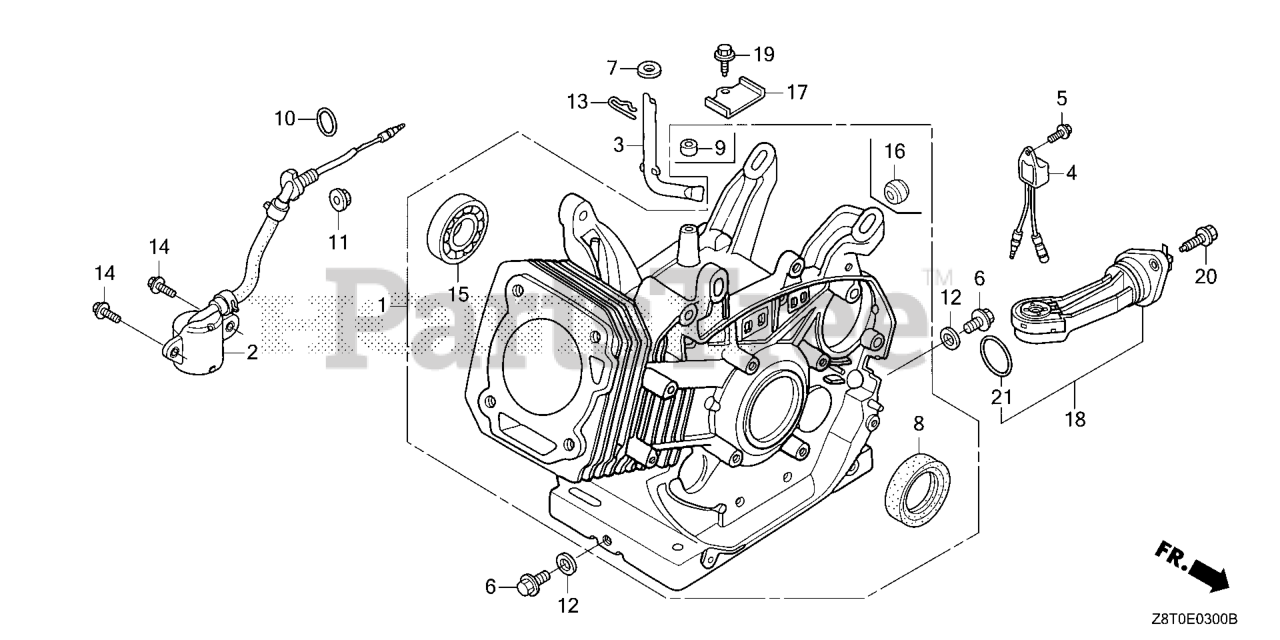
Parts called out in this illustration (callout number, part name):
1	CYLINDER ASSY. (ALERT)
2	SWITCH ASSY., OIL LEVEL
3	SHAFT, GOVERNOR ARM
6	BOLT, DRAIN PLUG
7	WASHER (8.2X17X0.8)
8	OIL SEAL (35X52X8) (NOK)
8	OIL SEAL (35X52X8)
9	OIL SEAL (8X14X5)
10	O-RING (14MM) (ARAI) Use up to Engine SN 2949254.
11	NUT, FLANGE (10MM)
12	WASHER, DRAIN PLUG (12MM)
13	PIN, LOCK (10MM)
14	BOLT, FLANGE (6X12) Use up to Engine SN 1543277.
15	BEARING, RADIAL BALL (6202) (FUJIKOSHI)
15	BEARING, RADIAL BALL (6202)
